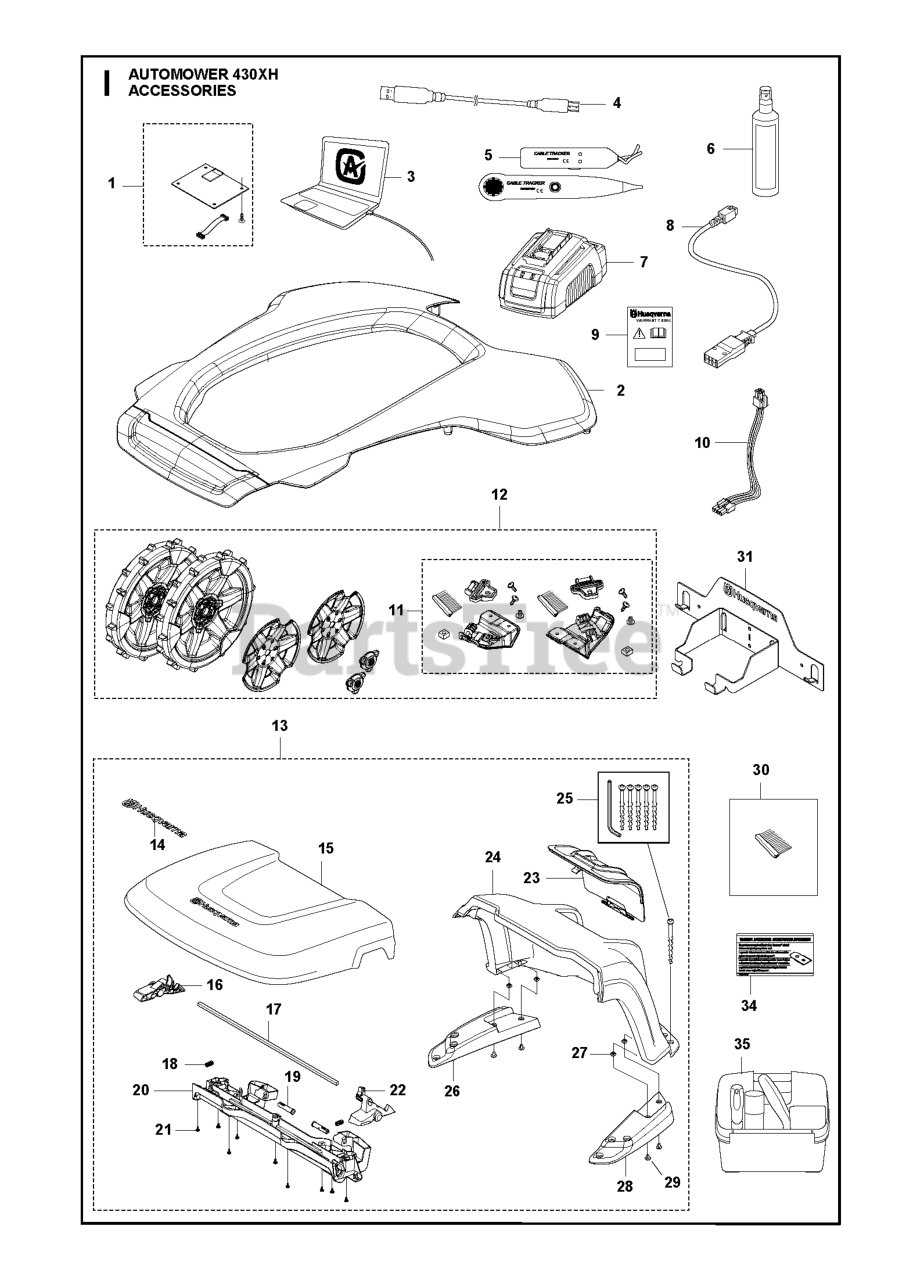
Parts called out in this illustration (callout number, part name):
2	BODY KIT WHITE 430X 2018+
2	BODY KIT ORANGE 430X 2018+
4	CABLE WHITE ALT GREY
5	TEST EQUIPMENT
7	CHARGER BATTERY TEST
8	CABLE ASSY QUICK CHARGER
9	LABEL WARRANTY SEAL DEALER
10	WIRING ASSY BATTERY CABLE
11	BRUSH KIT 430/450
12	REAR WHEEL KIT W/ BRUSHES
14	DECAL
16	HANDLE RELEASE LEFT
17	ROD
18	SPRING SPRING CAP
19	HINGE PIN
20	BEAM
21	SCREW 14MM
22	HANDLE RELEASE RIGHT
23	HATCH
26	SUPPORT BASE LEFT
27	NUT
28	SUPPORT BASE RIGHT
29	SCREW IHPANM M6X25 4.6 ZP-BC
30	WHEEL BRUSH REFILL KIT
34	DECAL WARNING ORIGINAL BLADE E
35	CLEANING AND MAITENANCE KIT AM
